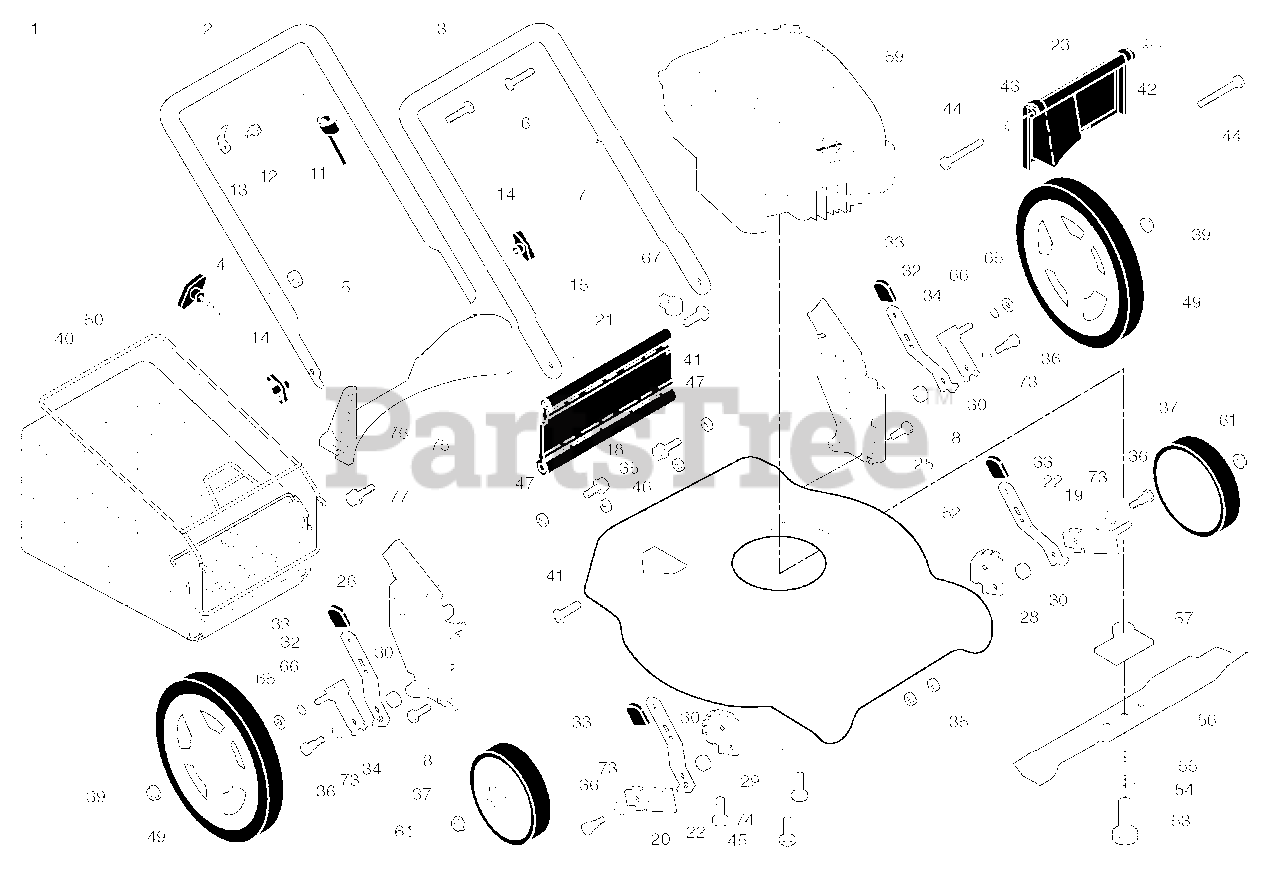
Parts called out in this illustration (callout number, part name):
1	Control Bar
2	Upper Handle
3	Lower Handle
4	Rope Guide
6	Handle Bolt
7	Wire Tie
8	Bolt, Hex Head 5/16-18 x 3/4
9	Hinge Bracket
10	Mulcher Door
11	Engine Zone Control Cable
12	Hex Washer Head Screw #10-24 x 1/2
13	Up-Stop Bracket
14	Handle Knob
15	Hairpin Cotter
18	Screw
19	Axle Arm Assembly, Front, LH
20	Axle Arm Assembly, Front, RH
21	Kit, Rear Skirt
22	Selector Spring, Front
23	Rear Door Assembly
25	Handle Bracket, LH
26	Handle Bracket, RH
28	Wheel Adjusting Bracket, Front, LH
29	Wheel Adjusting Bracket, Front, RH
30	Spacer
31	Discharge Deflector
32	Selector Spring, Rear
33	Selector Knob
34	Axle Arm Assembly, Rear, LH
35	Locknut, Hex 5/16-18
36	Shoulder Bolt 5/16-18
37	Wheel & Tire Assembly, Front 7 x 1-3/4
39	Nut, Hex
40	Frame, Grassbag
41	Screw, Hinge
42	Spring, LH
43	Spring, RH
44	Bolt, Rear Door
45	Hex Head Thread Rolling Screw 3/8-16 x 1
46	Danger Decal
47	Nut, Hex
48	Axle Arm Assembly, Rear, RH
49	Wheel & Tire Assembly, Rear 12 x 1-3/4
51	Hinge Rod
52	Kit, Housing
53	Screw, Hex Head, Grade 8 3/8-24 x 1-3/8
54	Helical Lockwasher
55	Hardened Washer
56	21" Blade
57	Blade Adapter
58	Hinge Spring
61	Flanged Locknut
62	Nut, Hex
65	Washer, Flat
66	O-Ring
67	Clip, Cable
73	Washer, Curved, Cylindrical
74	Washer, Special, Engine
75	Kit, Rear Baffle
76	Baffle, Rear
77	Screw, Rear Baffle
77	Operator's Manual, English
77	Operator's Manual, French
77	Repair Parts Manual
